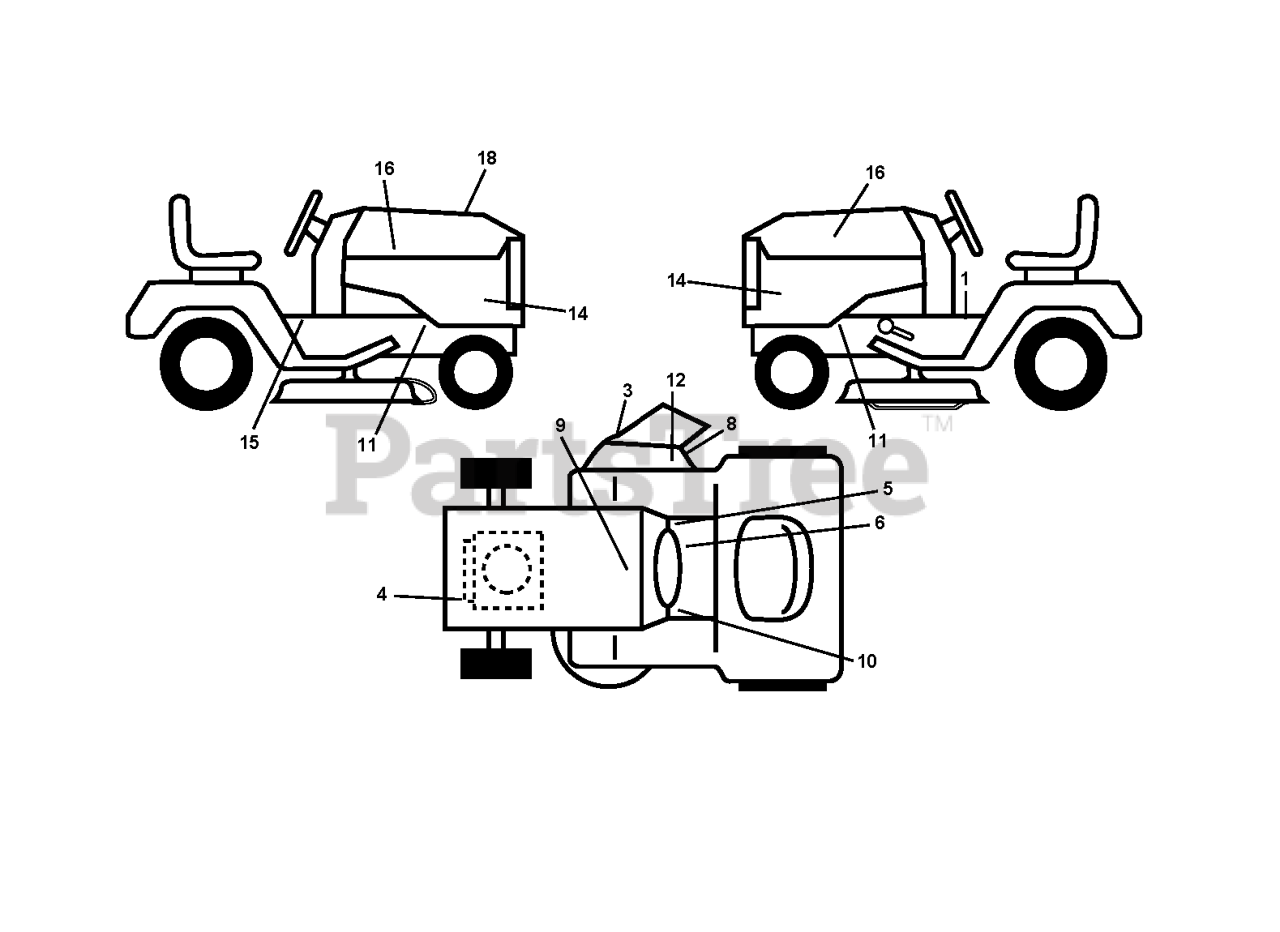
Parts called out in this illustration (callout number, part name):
1	LABEL
3	DECAL, DEFLECT WARNING
4	DECAL
5	DECAL PARK BRAKE
6	DECAL
8	DECAL.MOWER.SCH.48/54
9	DECAL BTRY SYMBOLS
10	DECAL
12	DECAL.INTERNATIONL.CUTFINGER
14	DECAL PNL SD.
15	DECAL.FENDER
16	DECAL.HOOD.NAMELOGO.HUSQ
18	DECAL RPL KO
